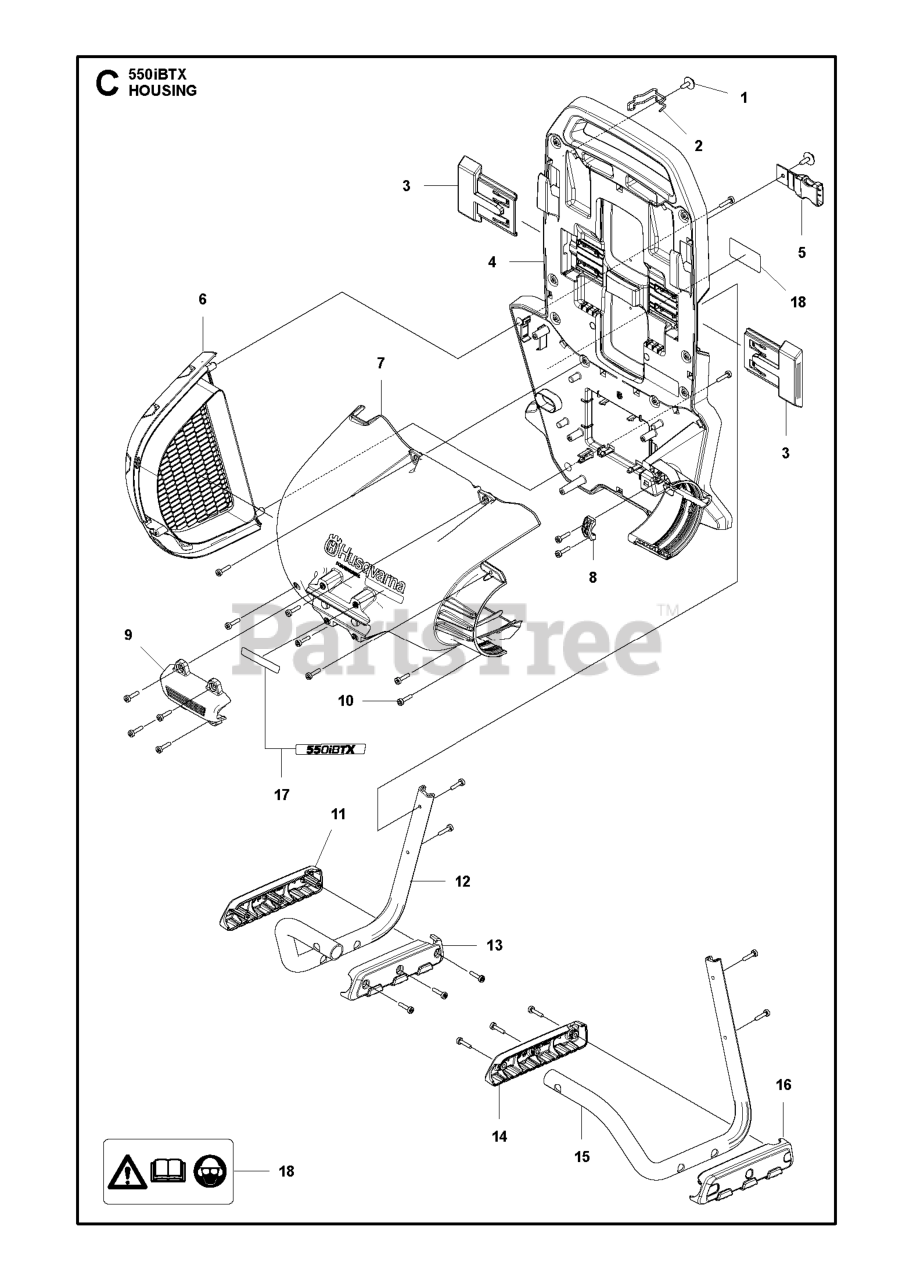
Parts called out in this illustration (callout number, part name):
1	SCREW ITXSCT MT5X16 10.9 TBO
2	HOLDER CABLE HOOK
4	BACKPLATE BACKPACK BATTERY BLO
5	STRAP BACKPLATE FEMALE
7	COVER BACKPACK BATTERY BLOWER
8	CABLE CLAMP
9	COVER FRONT COVER BUMPER
10	SCREW ITXSCT PW4.2X18 10.9 ZN
11	HOUSING RIGHT FOOT THREAD SIDE
12	FRAME RIGHT BUMPER
13	HOUSING RIGHT FOOT SCREW SIDE
14	HOUSING LEFT FOOT SCREW SIDE
15	FRAME LEFT BUMPER
16	HOUSING LEFT FOOT THREAD SIDE
